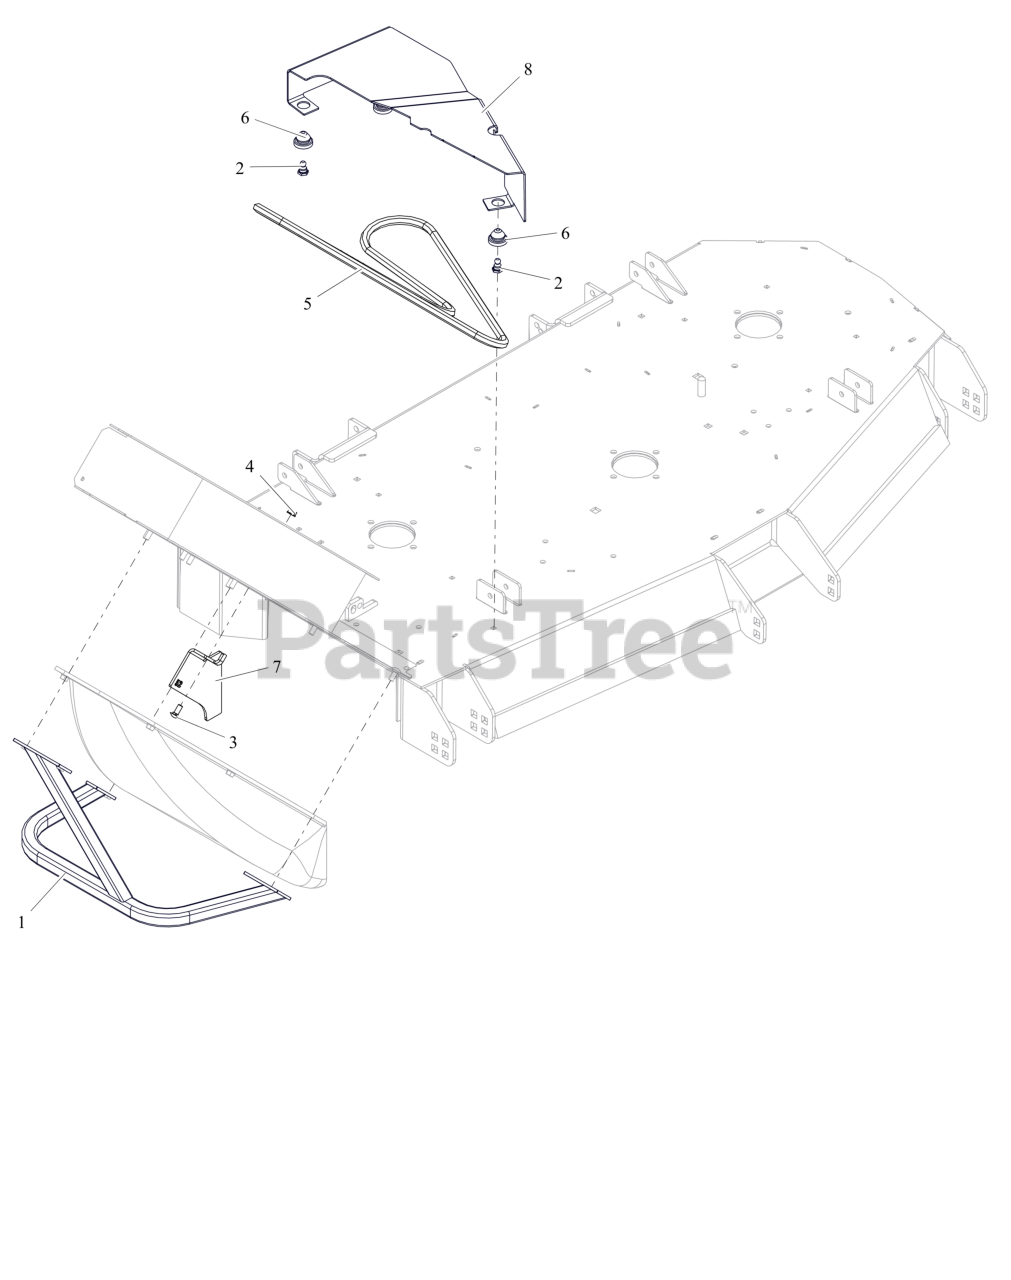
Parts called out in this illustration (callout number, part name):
1	WLDMT, BLOWER GUARD (BLACK)
2	STUD, BALL FEMALE .250-20 THREAD
3	BLT, RHSSN.31-18X.750 G5 ZCC
4	NUT,LK-CTR-FLG .31-18 GF ZCC
5	HEX BELT, HAA SECTION
6	COUPLING, RUBBER PUSH-IN
7	BRKT, PT600 52" BAGGER DISCH (BLACK)
8	GUARD, RH BLOWER DECK BELT (BLACK)
